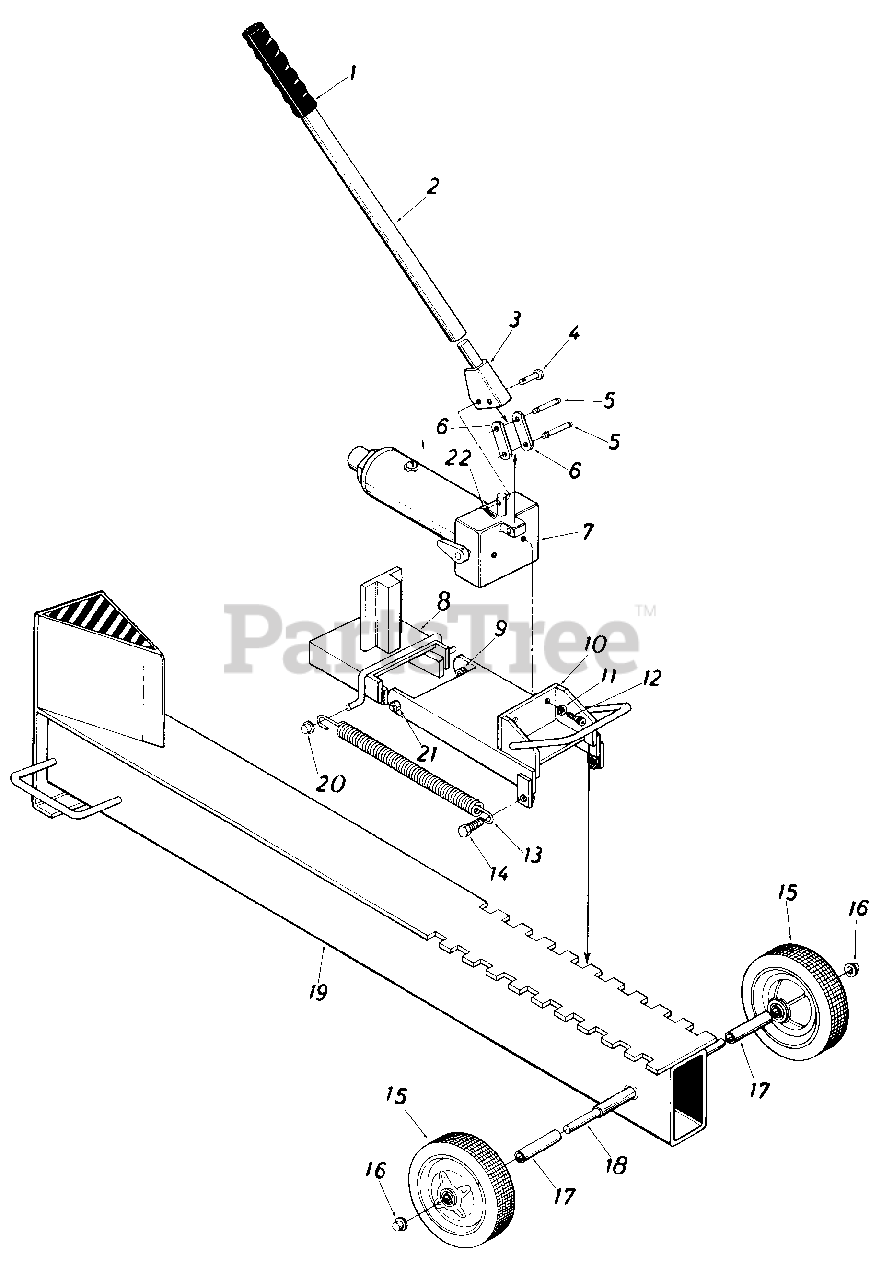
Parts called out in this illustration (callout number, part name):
1	Handle Grip
2	Handle 3/8" Dia. Rod
3	Handle Socket
4	Clevis Pin
5	Pin & Ring Assembly
7	Hydraulic Pump & Cylinder
8	Push Plate Ass'y.
9	Socket Hd. Bolt 1/2-13 x 75" Lg.
10	Cylinder Mounting
11	L.-Wash. 3/8" I.D.*
12	Socket Hd. Bolt 3/8-16 x .75" Lg.
13	Extension Spring .75" O.D. x 10.75" Lg.
14	Hex L.-Bolt 3/8-16 x .75" Lg.*
15	Wheel 7.0" x 1.75"
16	1/2" Push Cap
17	Spacer
18	Axle 1/2" Dia. x 12" Lg.
19	Tube and Rail Ass'y.
20	1/2" Push Cap
21	Hex Cent. L.-Nut 1/2-13 Thd.
22	Hair Pin Cotter
